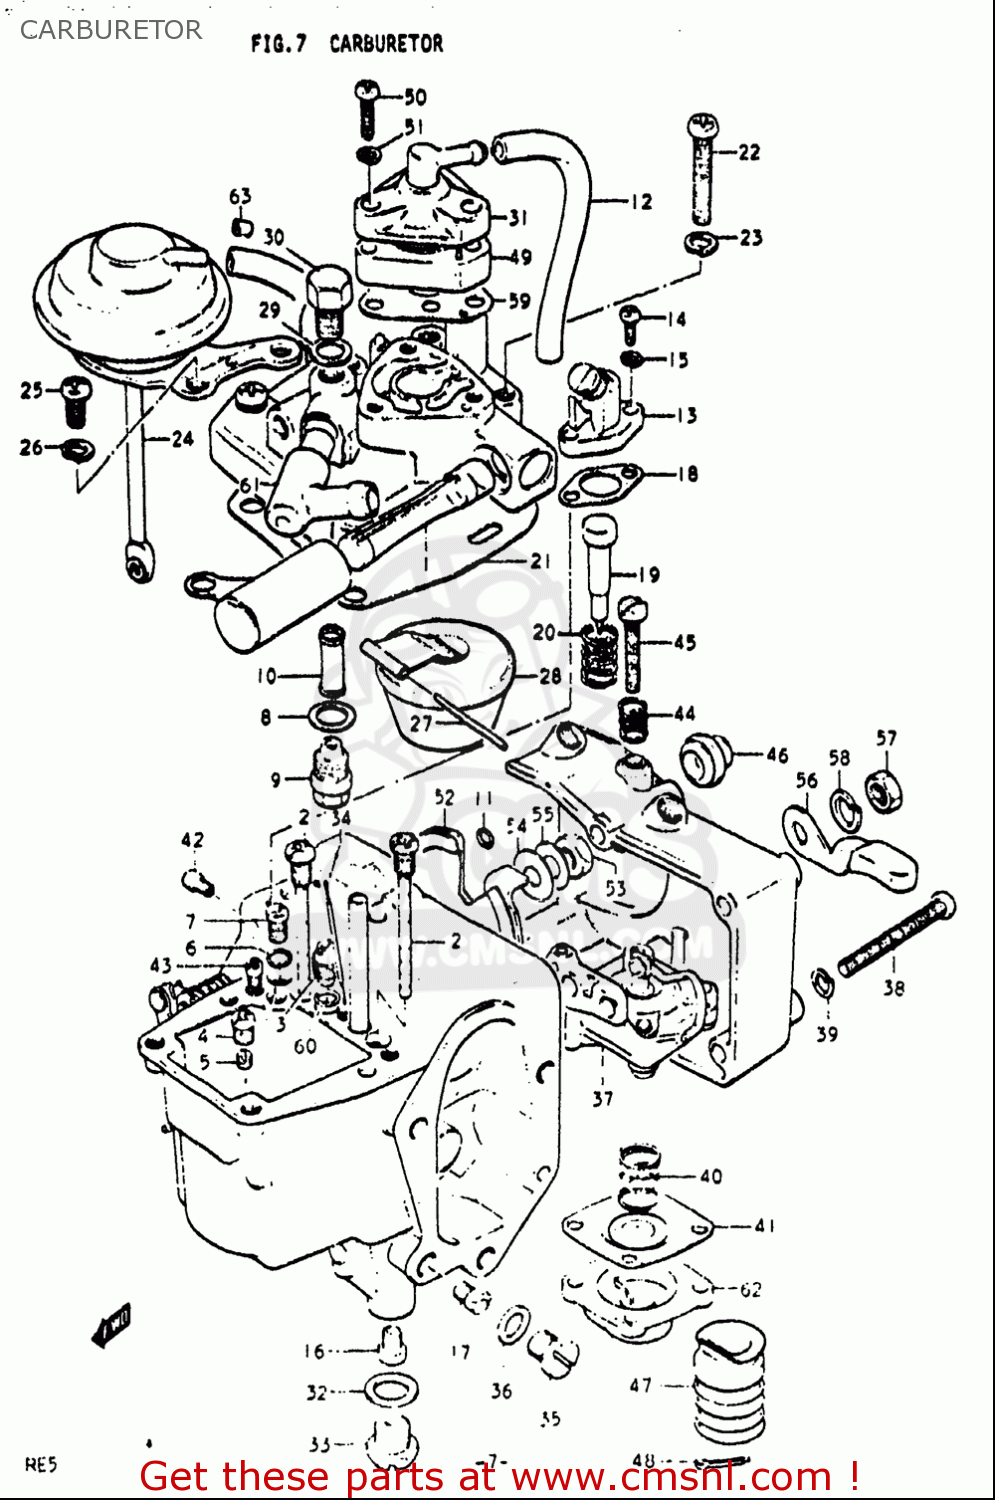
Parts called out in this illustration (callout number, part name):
4	JET,AIR(140)
5	JET,PILOT(70)
6	O RING
7	JET,PILOT(45)
8	GASKET,MAIN JET HOLDER (NAS)
14	SCREW
15	WASHER,LOCK
17	JET,MAIN(90)
20	SPRING,THROTTLE SCREW
22	SCREW
23	WASHER,LOCK
25	SCREW
26	WASHER,LOCK
27	PIN, FLOAT
29	WASHER, VALVE SEAT
35	BOLT
38	SCREW
39	WASHER,LOCK
41	DIAPHRAGM
43	JET
44	THROTTLE SCREW
51	WASHER,LOCK
53	NUT
58	WASHER,LOCK
59	GASKET,ENRICHMENT (MCA)
